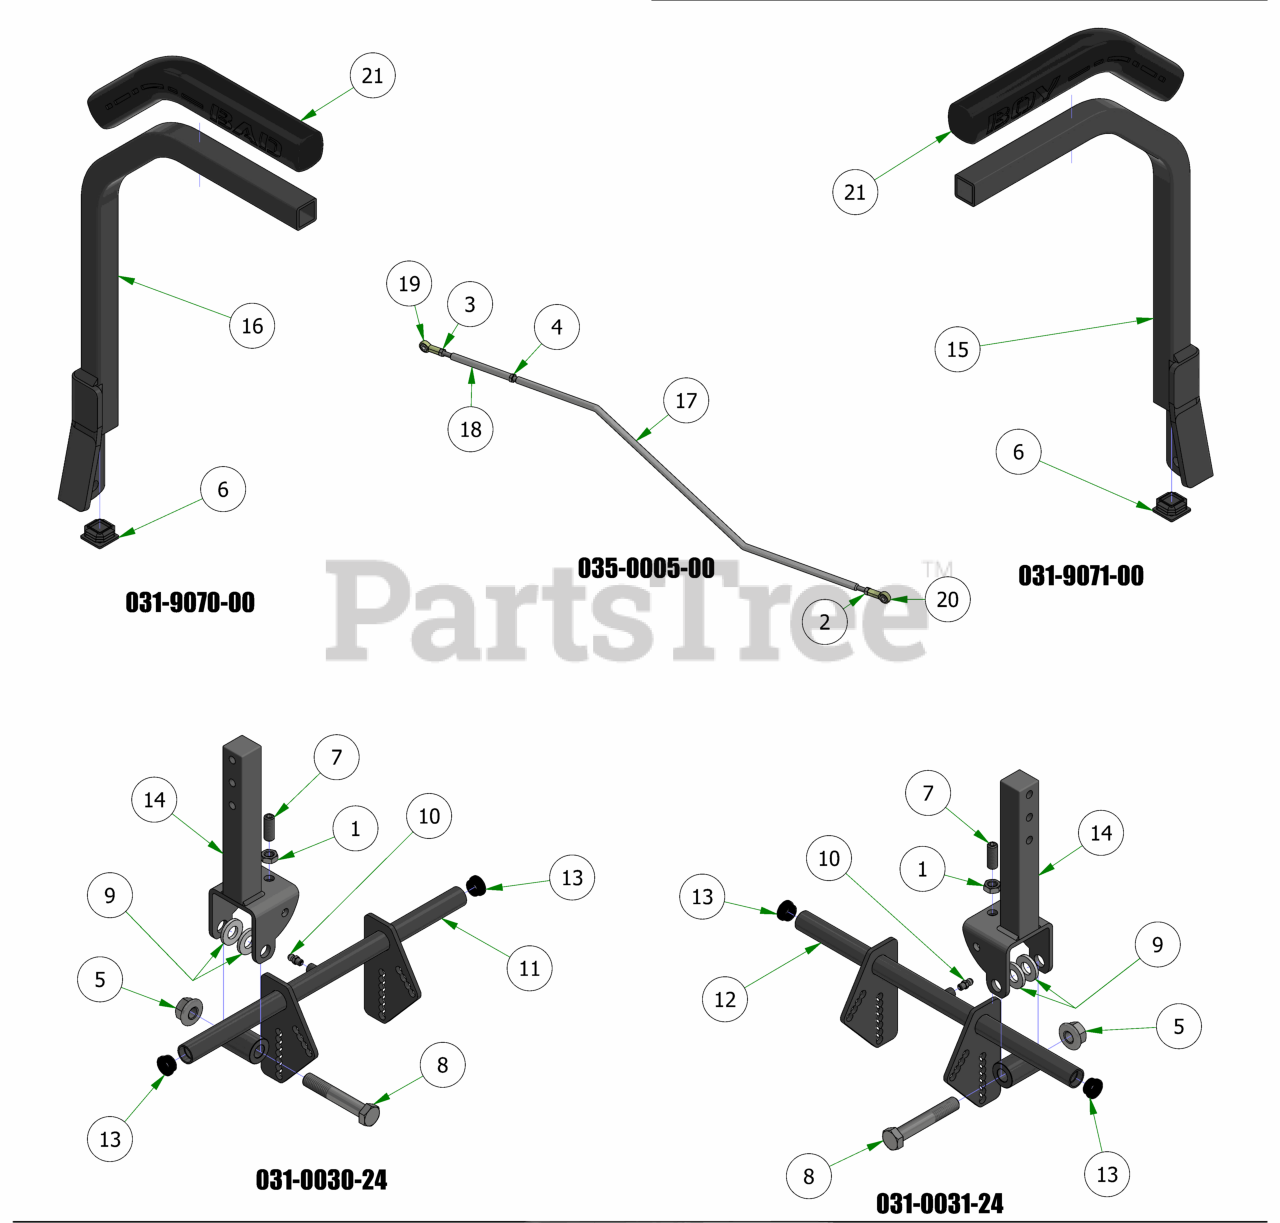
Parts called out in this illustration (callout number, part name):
1	3/8-16 Half Jam Nut
2	5/16 RH Nut
3	5/16 LH Nut
4	3/8-24 HEX NUT ZINC YELLOW
5	1/2-13 NYLON INSERT FLANGE LOCKNUT ZINC
6	9565K52_Polyethylene Square Plug
7	3/8-16 X 1 SOCKET SET SCREW (CUP POINT) PLAIN
8	1/2-13 X 3 HEX CAP SCREW (GR.5) ZINC
9	.505 ID X 1.000 OD X .125 THICK FLAT WASHER NYLON
10	1/4 DRIVE-TYPE STRAIGHT GREASE FITTING ZINC YELLOW)
11	2019 Drive Arm Actuator right - Weldment
12	2019 Drive Arm Actuator left - Weldment
13	2019 Drive Arm Bushing
14	R Series Square Drive Arm Pivot
15	R Series Square Drive Arm LH Weldment
16	R Series Square Drive Arm RH Weldment
17	2019 Renegade Push Rod
18	2019 Renegade Push Rod Adjuster
19	Spherical Rod End - Outlaw
20	Spherical Rod End - Outlaw
21	R-Series Square Drive Grip
